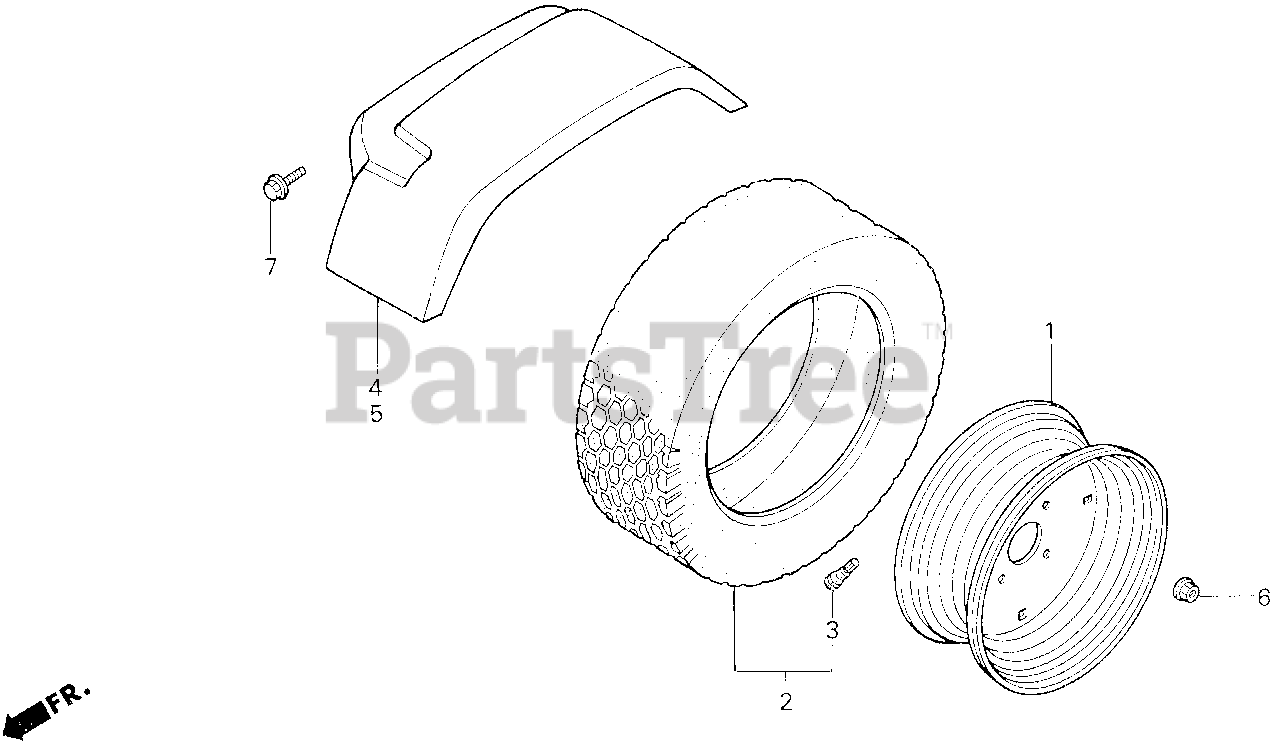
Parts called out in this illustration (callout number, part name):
1	WHEEL (14X6JJ)
2	TIRE ASSY., RR. (24X8.00-14) (2PR) (OHTSU)
3	VALVE, RIM
4	FENDER, R. RR. *R136* (DIANA RED)
5	FENDER, L. RR. *R136* (DIANA RED)
6	NUT, WHEEL (12MM)
7	BOLT, FLANGE (8X16)
